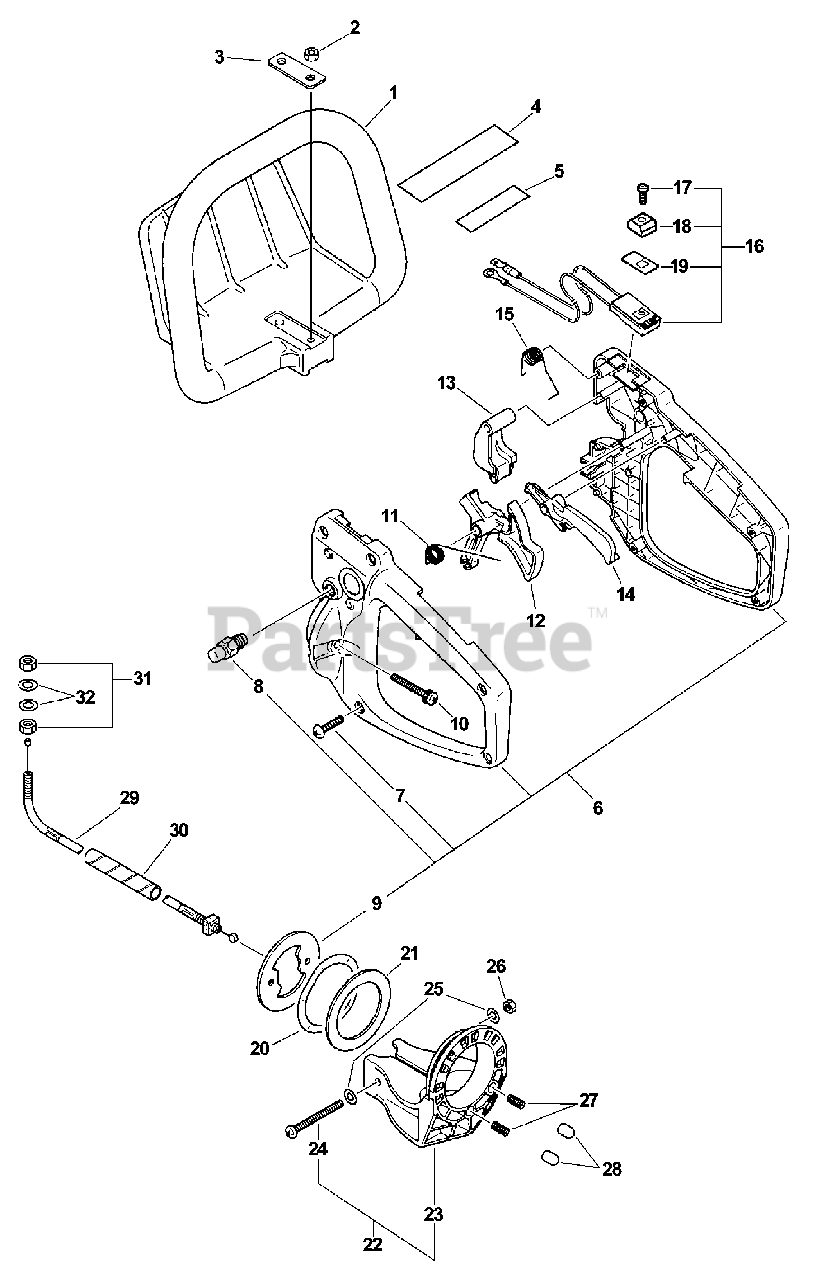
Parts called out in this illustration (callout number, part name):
1	HANDLE - FRONT
2	LOCKNUT - 5
4	LABEL - CAUTION
5	LABEL - CAUTION
6	HANDLE ASSY - REAR
7	SCREW - 4X16
8	LOCK, THROTTLE
9	BRACKET, HANDLE
10	SCREW - 5X30
12	TRIGGER, THROTTLE
14	LOCKOUT, THROTTLE
15	SPRING, TRIGGER
16	IGNITION SWITCH ASSY
17	KNOB, SWITCH - ORANGE
18	SCREW - 3X10
19	COVER, SWITCH - STOP
20	WASHER
21	WASHER - 50
22	BRACKET, HANDLE
23	BRACKET, HANDLE
24	SCREW - 5X40
25	WASHER - 5
26	LOCKNUT - 5
27	SPRING, TRIGGER
29	CABLE, THROTTLE
30	TUBE
31	NUT - 6
32	WASHER - 6
